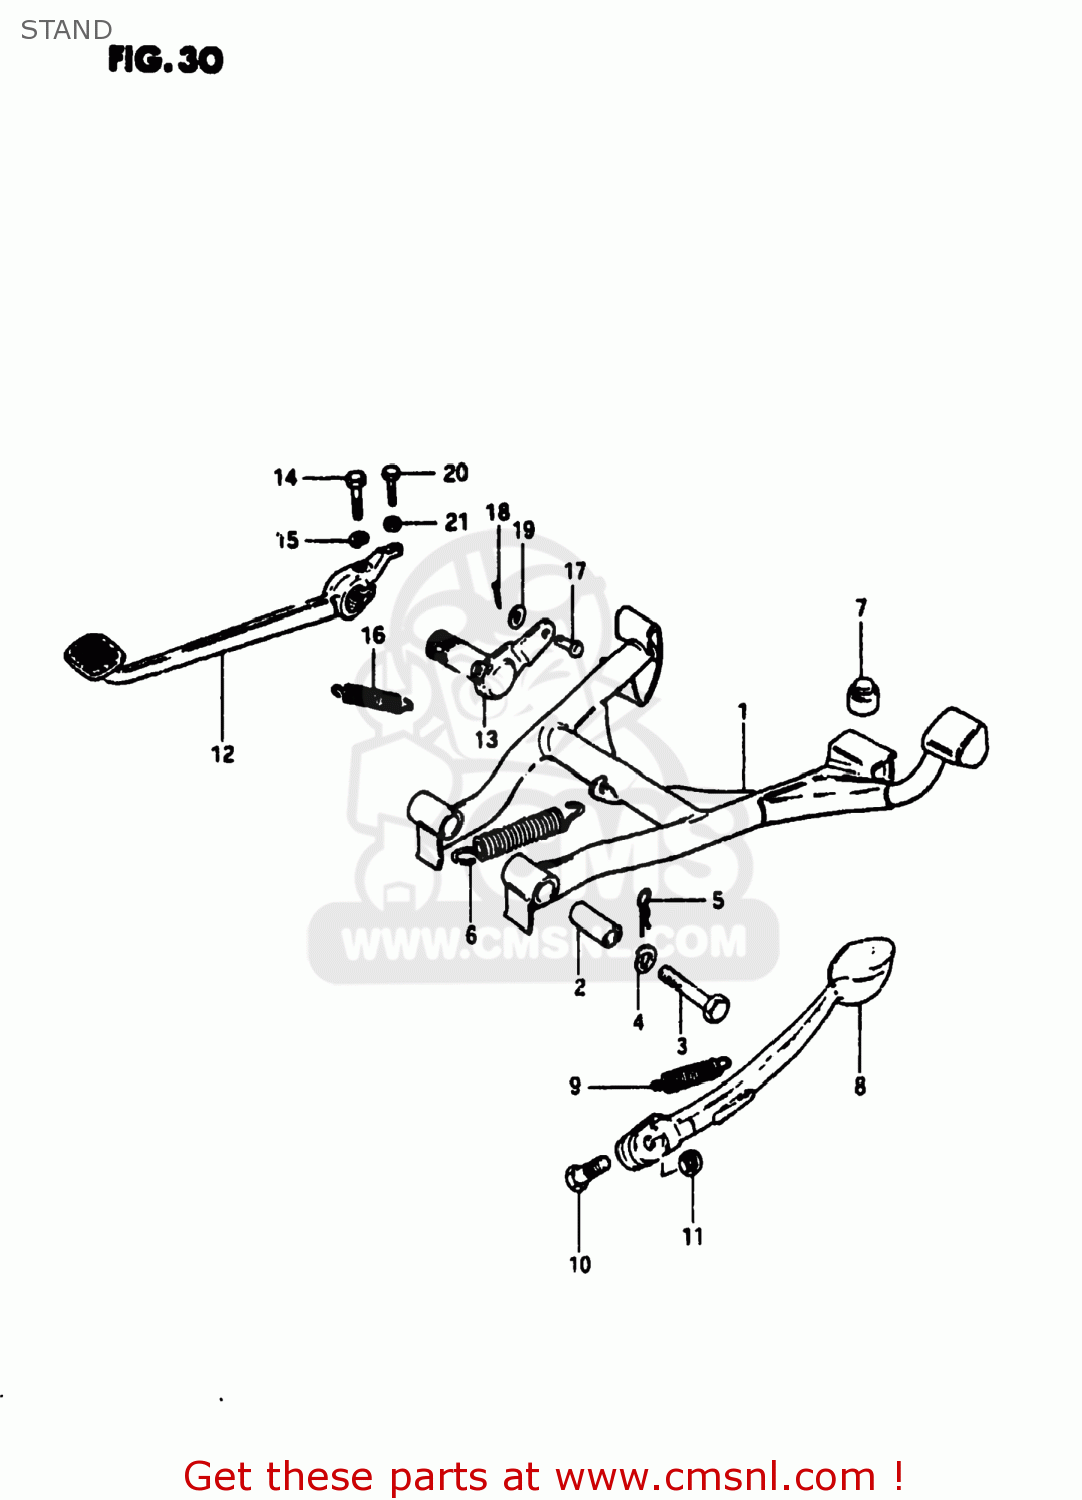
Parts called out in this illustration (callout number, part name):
1	STAND,CENTER
2	SPACER(10X16X38.8)
3	BOLT
4	LOCK WASHER
5	CLIP
6	SPRING
7	CUSHION
8	STAND,SIDE
9	SPRING
10	BOLT(10X30)
11	NUT
12	PEDAL,BRAKE
13	ARM,BRAKE PEDAL ROD
14	BOLT
15	LOCK WASHER
16	SPRING
17	PIN
18	PIN
19	WASHER
20	BOLT
21	NUT
